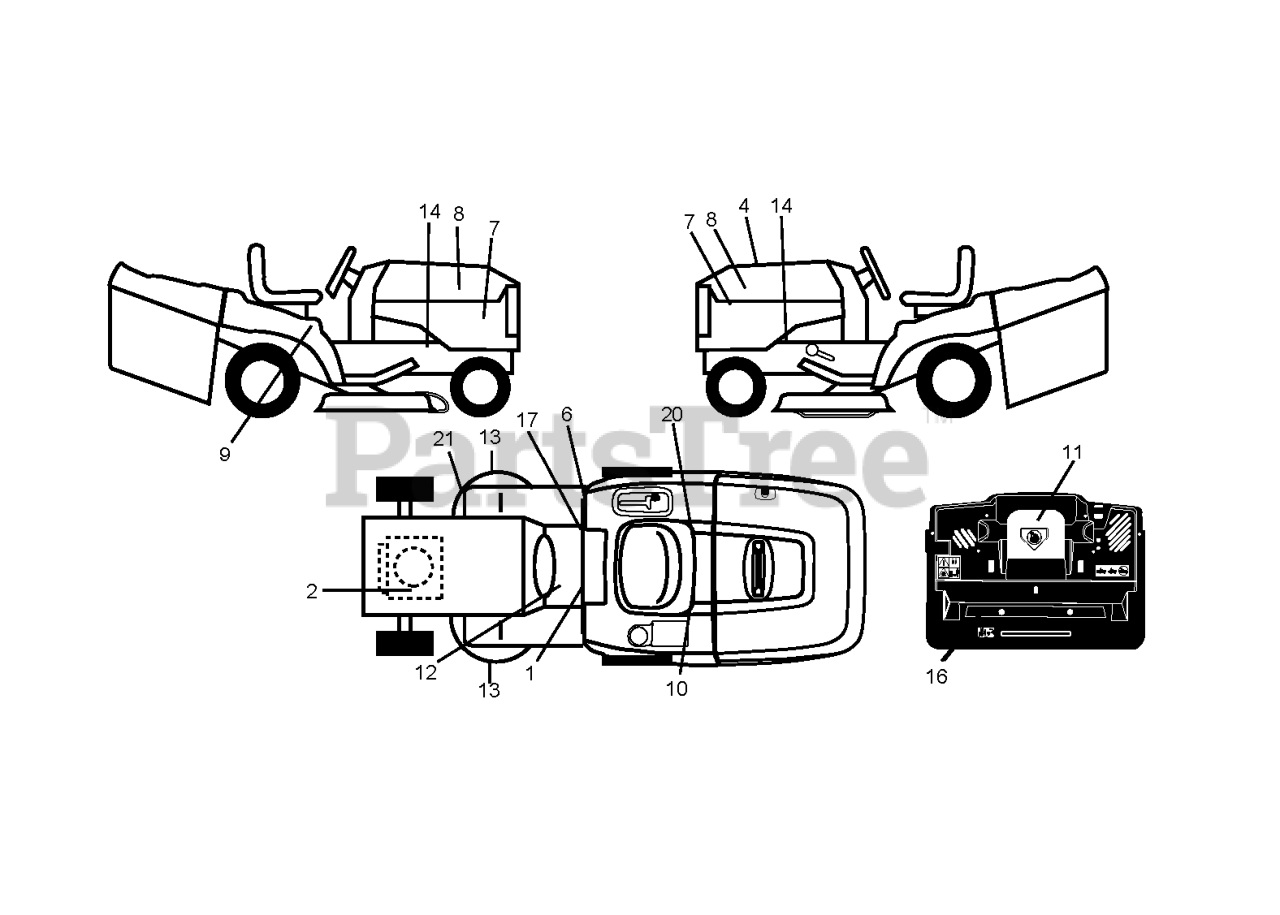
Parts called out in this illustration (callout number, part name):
1	LABEL
2	DECAL
6	Decal, Fender 100 DB/CE
8	DECAL.HOOD.NAMELOGO.HUSQ
9	Decal, Fender 100 DB/CE
10	DECAL BTRY SYMBOLS
11	DECAL.INTERNATIONL.CUTFINGER
12	DECAL
16	DECAL
17	DECAL PARK BRAKE
20	DECAL.BYPASS.FENDER.CRD.LT.YT
